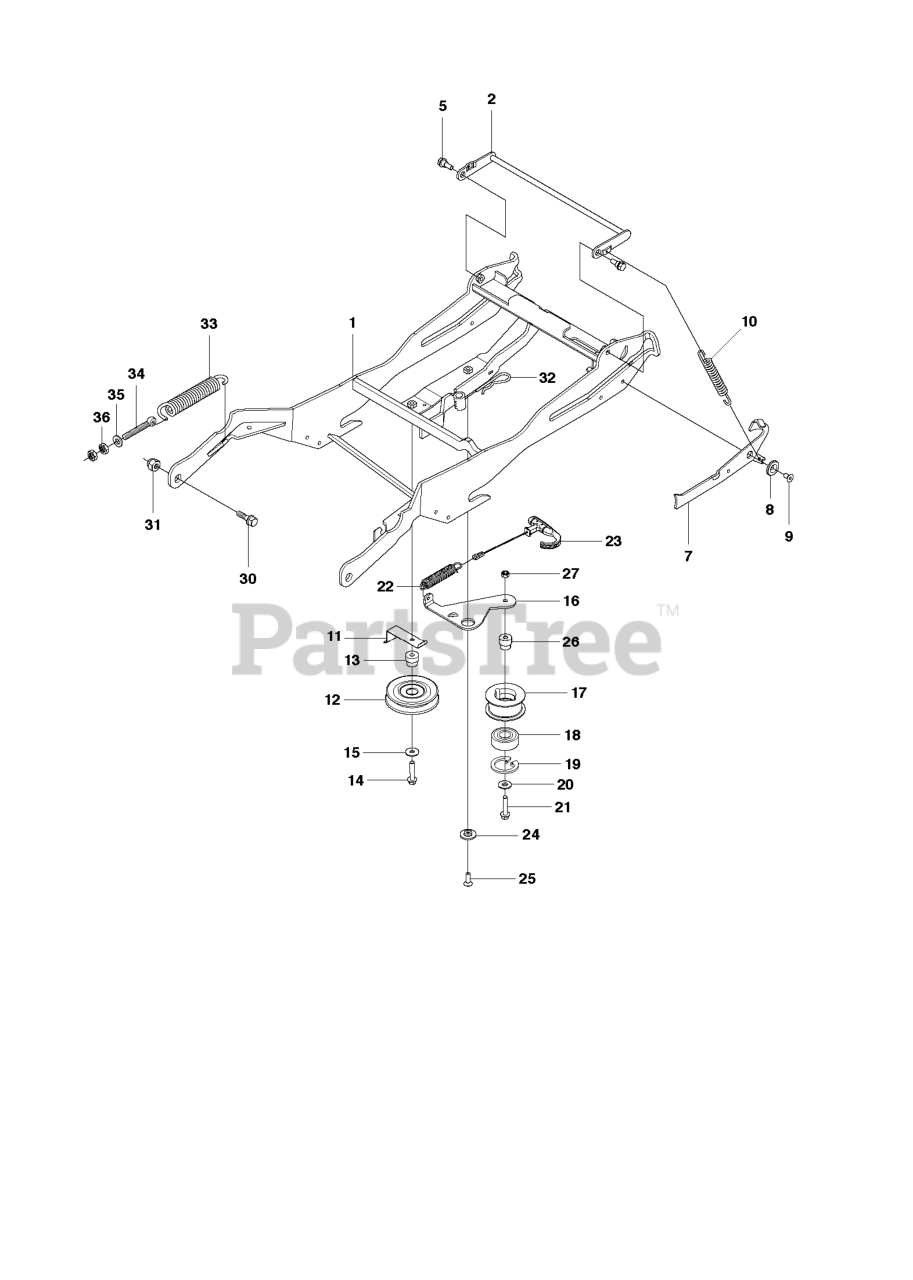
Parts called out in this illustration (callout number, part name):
1	EQUIPMENT FRAME
8	SPACER
9	SCREW IHCSFM
11	BELT GUIDE
18	BALL BEARING 6004-2RS1
19	RETAINING RING
23	HANDLE ASSY
24	WASHER
27	LOCKNUT M8
35	WASHER
36	NUT
